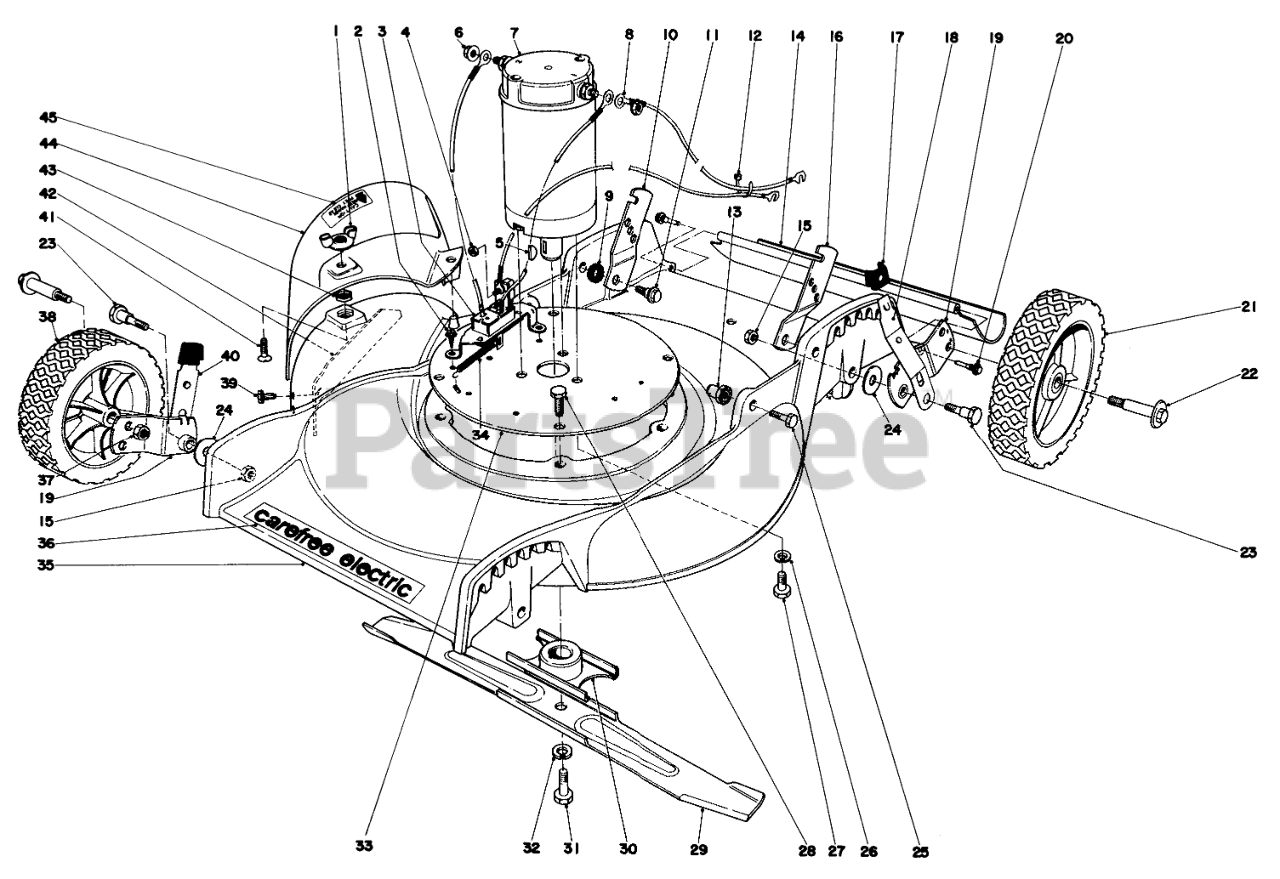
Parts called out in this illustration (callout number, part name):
1	NUT-WING SPECL
2	SCREW-HWHTF
3	Switch
4	NUT-HEX
5	KEY-WOODRUFF
6	Nut Belleville
7	Motor
8	Lead-Ground (Black)
9	SPACER
10	Latch Handle R.H.
11	SCREW-SHOULDER
12	TIE-CABLE
13	HANDLE PIVOT NUT
14	Rear Safety Shield
15	Nut
16	Latch Handle L.H.
17	KNOB-ARM
18	Spring Arm Assy. Rear
19	Pivot Arm Assy. "A"
20	SAFTEY SHIELD SCREW
21	WHEEL ASM 7
23	Pivot Bolt
24	WASHER-PIVOT
25	SCREW-HH
26	WASHER-LOCK
27	SCREW-HH
28	SCREW-HWHTF
29	Blade
30	Blade Retainer
31	Capscrew
32	WASHER-LOCK
33	Plate Motor Mount
34	Spring Extension-Return
35	Housing
36	Decal-Deck
37	Nut
38	Wheel & Tire Assembly, Front
39	SCREW-HWH
40	Spring Arm Assy. Front
41	Flat Head Screw
42	Deflector Bar
44	Deflector Assy. (Incl. Ref. #45)
45	Decal
